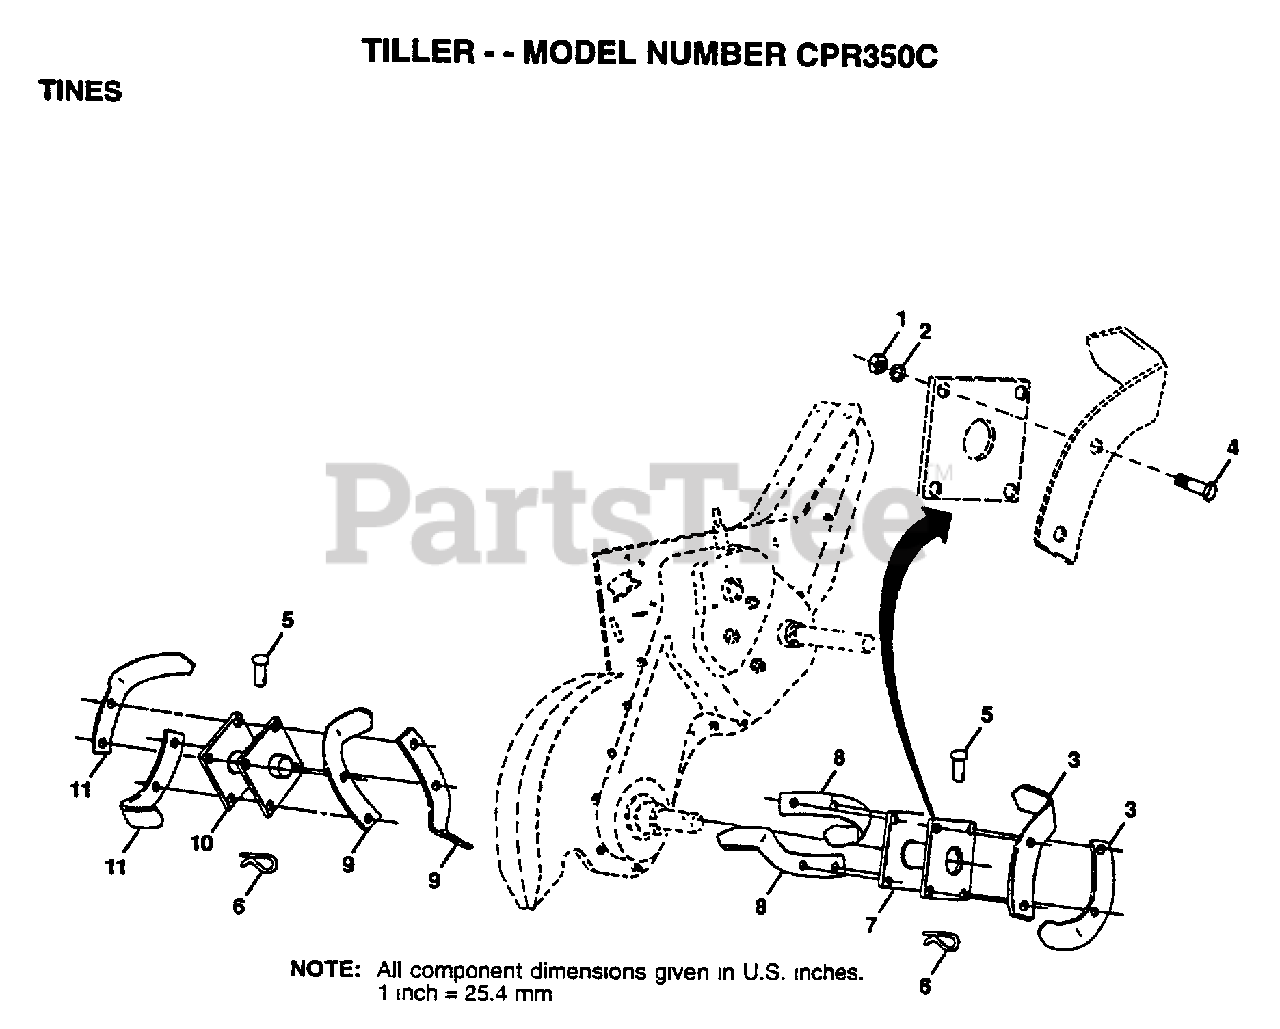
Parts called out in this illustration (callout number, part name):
2	LOCKWASHER
4	BOLT
5	PIN.CLEVIS.SHEAR
6	RETAINER.SPRING
7	ASM HUB&PLATE RH
8	"TINE.RH.12"""
9	"TINE.LH.12"""
10	ASM HUB&PLATE LH
